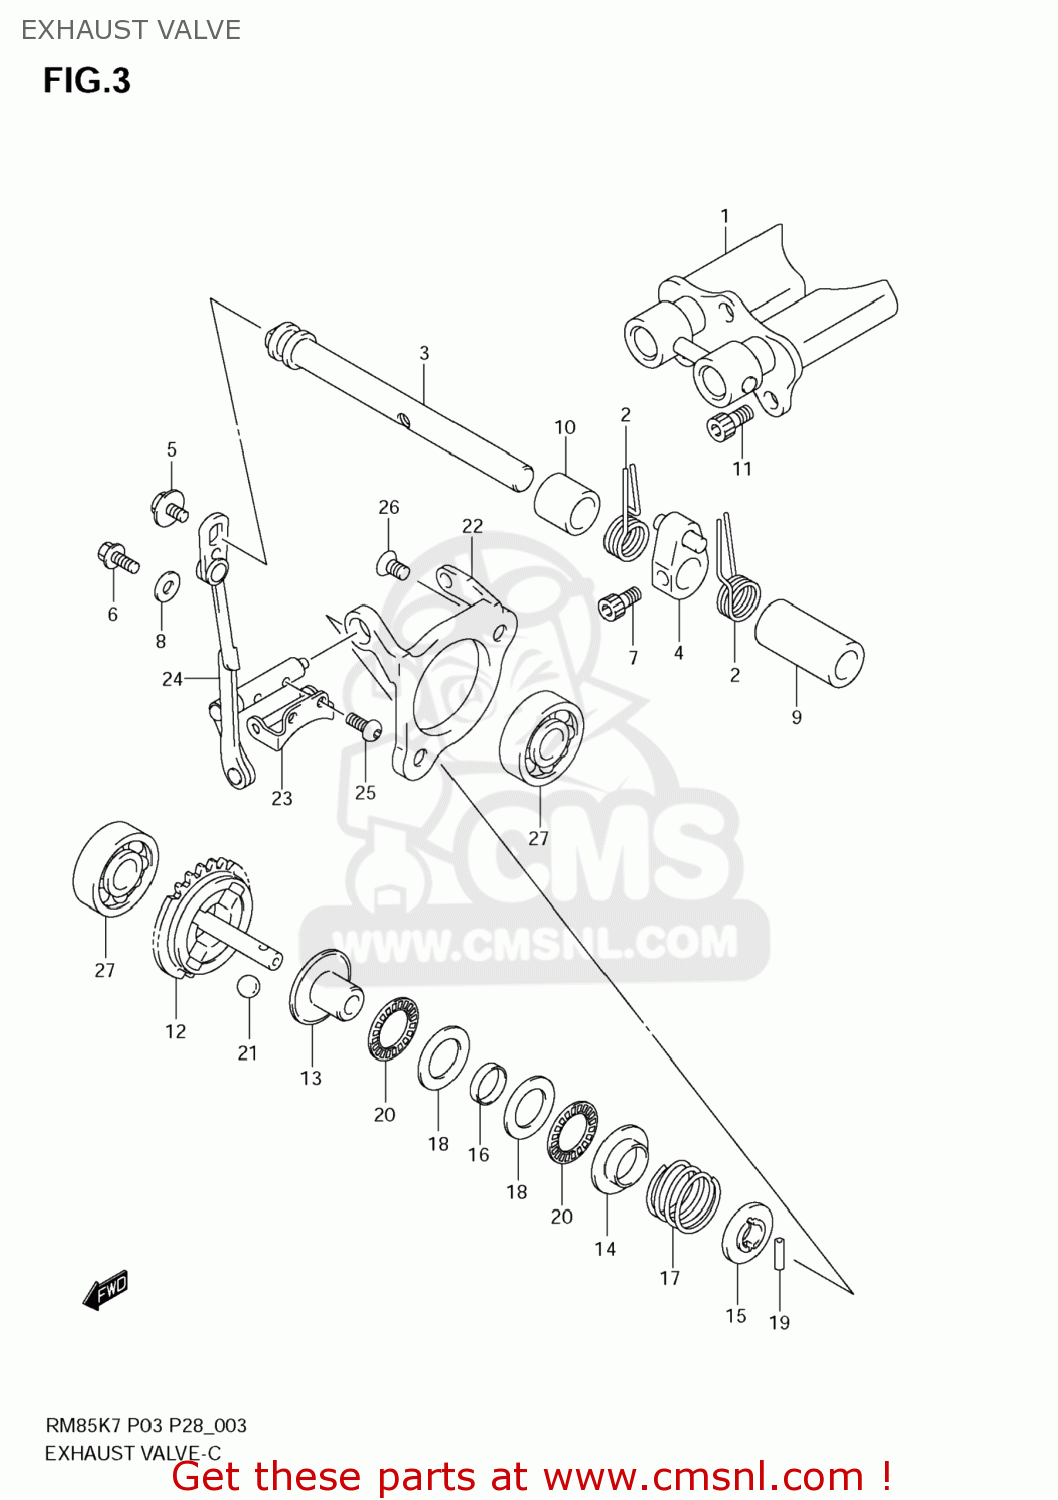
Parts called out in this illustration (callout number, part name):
1	VALVE ASSY,EXHAUST VALVE
2	SPRING,EXHAUST VALVE SHAFT ARM
3	SHAFT,EXHAUST VALVE
4	ARM,EXHAUST VALVE SHAFT
5	BOLT(5X10)
6	BOLT(6X10)
7	BOLT(4X8)
8	WASHER(6.5X14X2.3)
9	SPACER(8.4X12X13)
10	SPACER(8.5X12X11)
11	BOLT
12	GOVERNOR SET,EXHAUST
13	GOVERNOR,DRIVEN
14	STOPPER,GOVERNOR SPRING NO.1
15	STOPPER,GOVERNOR SPRING NO.2
16	SPACER,GOVERNOR
17	SPRING,GOVERNOR
18	SHIM(15X28X1)
19	ROLLER(3X12.5)
20	BEARING(15X28X2)
21	BALL
22	BASE,ACTUATOR
23	ARM,ACTUATOR
24	ACTUATOR,EXHAUST VALVE
25	BOLT(4X8)
26	SCREW(5X10)
27	BEARING(8X22X7)
